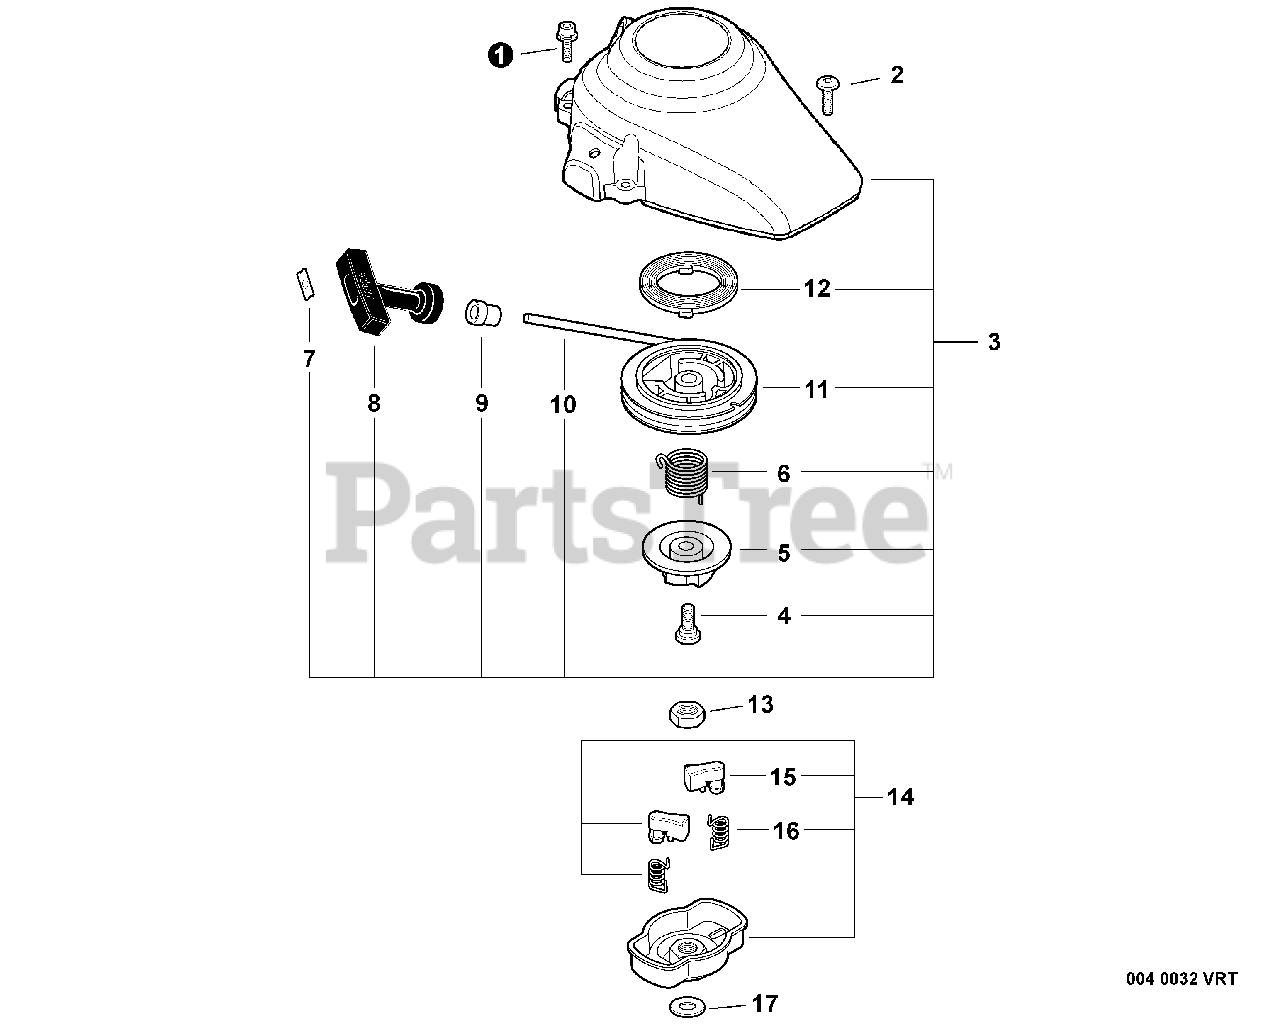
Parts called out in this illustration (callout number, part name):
1	SCREW - 4X16
2	SCREW - 4
3	STARTER ASSY
4	SCREW
5	CATCHER, PAWL
7	RETAINER, ROPE
8	GRIP, STARTER
9	GUIDE, ROPE
10	ROPE, STARTER - 3X700
11	REEL, ROPE
12	SPRING, REWIND
13	NUT - LEFT HAND
14	STARTER PAWL ASSY
15	PAWL, STARTER
16	SPRING, RETURN
17	WASHER - 8
